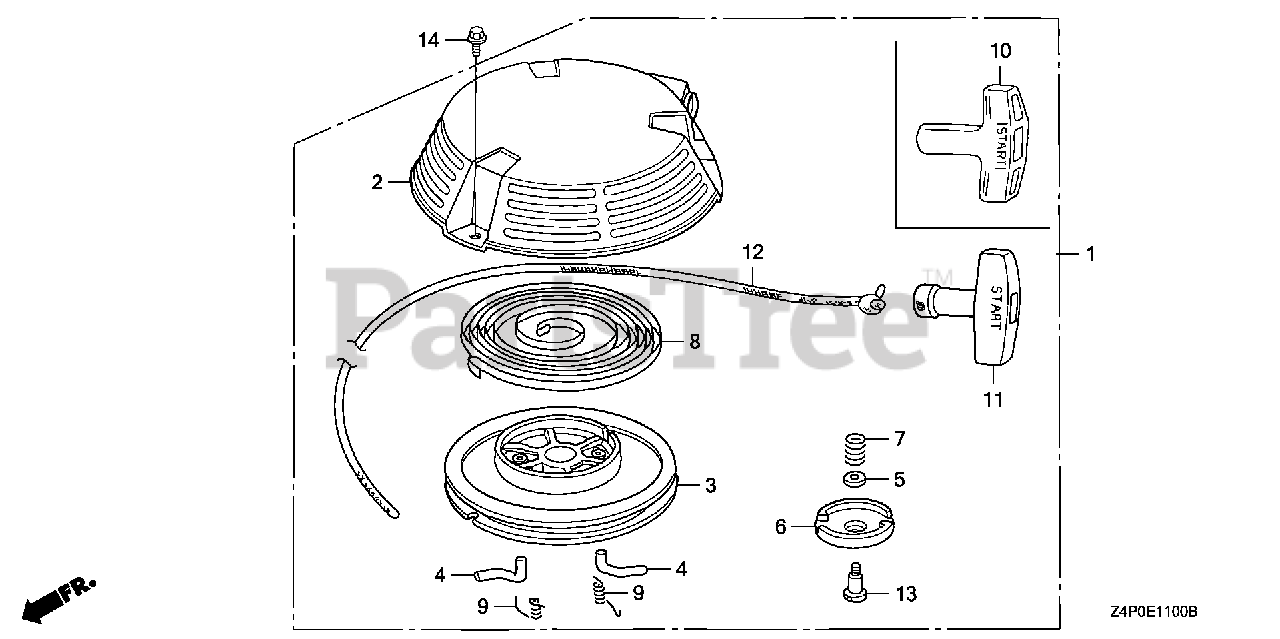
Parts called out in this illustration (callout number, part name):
1	STARTER ASSY., RECOIL *NH1* (BLACK)
1	STARTER ASSY., RECOIL *R280* (POWER RED)
2	CASE, RECOIL STARTER *R280* (POWER RED)
2	CASE, RECOIL STARTER *NH1* (BLACK)
3	REEL, RECOIL STARTER (BLACK)
4	RATCHET, STARTER
5	PLATE, FRICTION
6	GUIDE, RATCHET
7	SPRING, FRICTION
8	SPRING, RECOIL STARTER
9	SPRING, RETURN
11	GRIP, STARTER
12	ROPE, RECOIL STARTER (#5X55")
13	SCREW, SETTING
14	BOLT, FLANGE (6X8)
